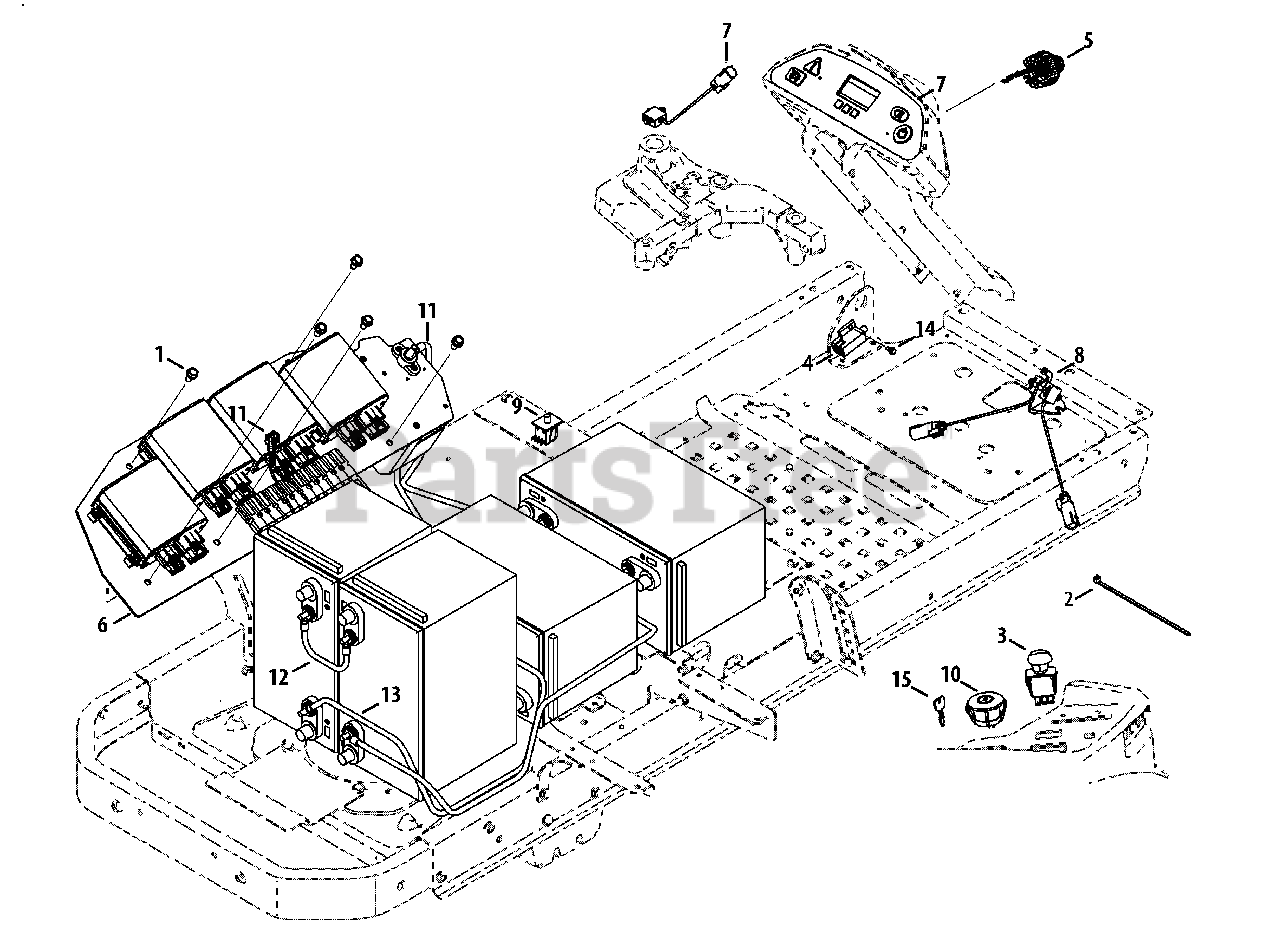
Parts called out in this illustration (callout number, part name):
1	Hex Washer Screw, 5/16-18 x .750
2	Cable Tie
3	Switch, Electric PTO, Yellow Knob
4	Interlock Switch
5	LED Headlight Socket
6	Controller Assembly
7	Control Module Assembly
8	Throttle Sensor
9	Seat Switch
10	Key Switch
11	Electric Battery Harness, 48V
12	Electric Battery Harness, 24V
13	Electric Battery Harness, 12V, 36V
14	Shoulder Screw, #10-32 x .500
15	Key, Assembly
